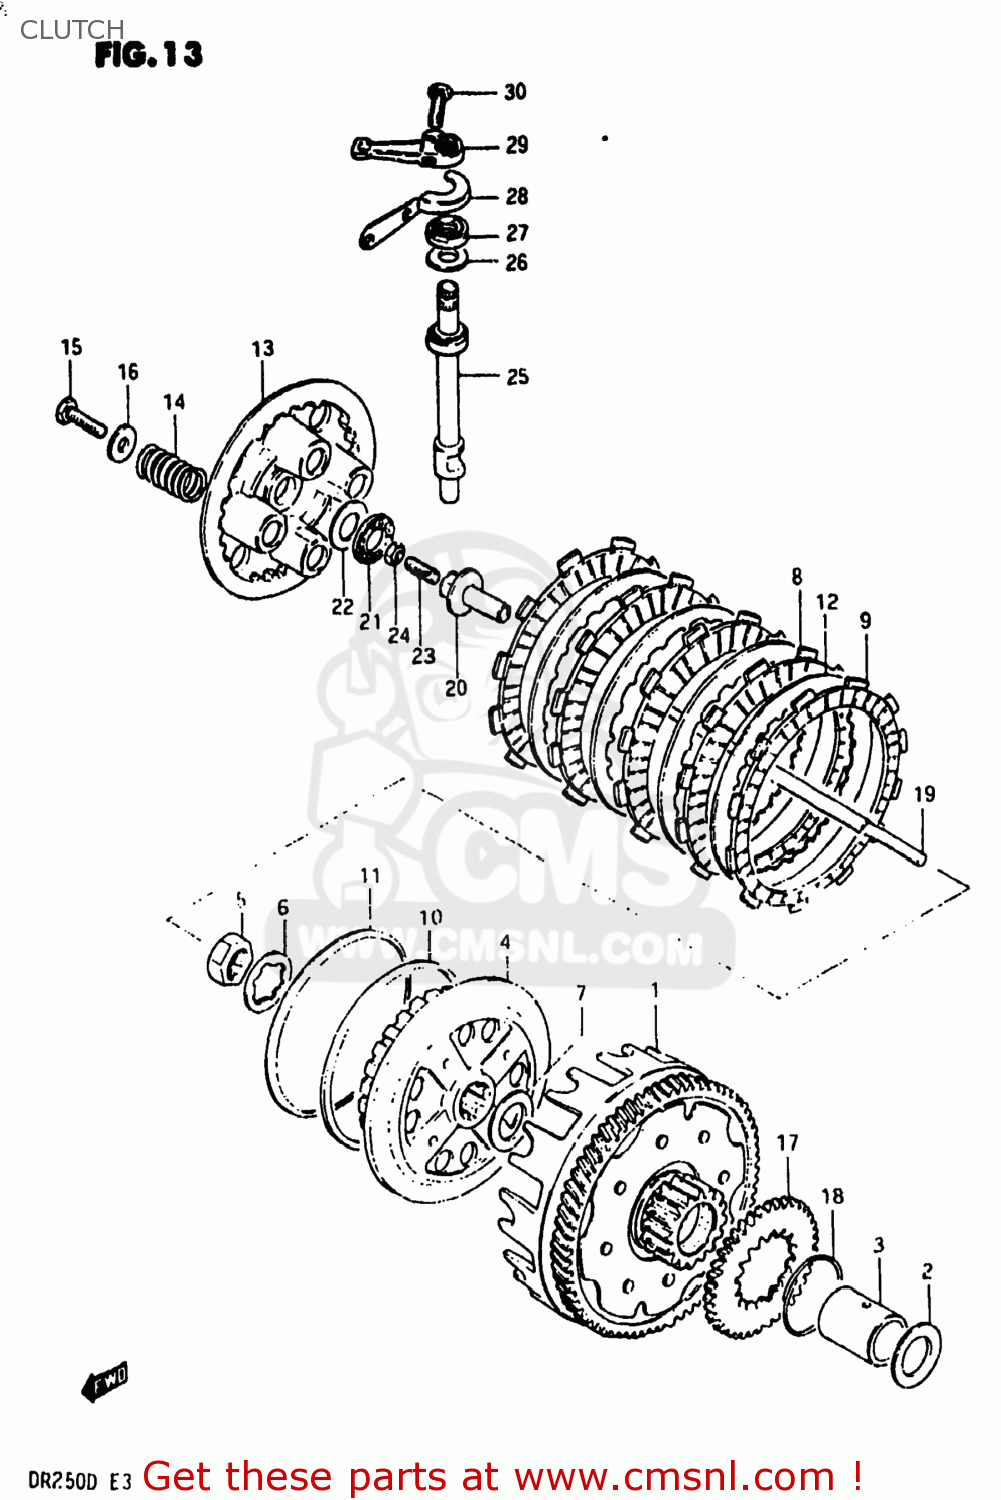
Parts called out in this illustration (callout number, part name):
1	GEAR ASSEMBLY,PRIMARY DRIVE
2	WASHER
3	SPACER(22X28X37.5)
4	HUB,CLUTCH SLEEVE
5	NUT
6	WASHER,LOCK
7	WASHER
8	PLATE,CLUTCH DRIVE (MCA)
9	PLATE,CLUTCH DRIVE
10	SEAT,WAVE WASHER(T:1.4)
11	WASHER
12	PLATE,CLUTCH DRIVEN
13	DISC,CLUTCH PRESSURE
14	SPRING
15	BOLT, UPPER
16	WASHER
17	GEAR,OIL PUMP DRIVE
18	CIRCLIP
19	ROD,CLUTCH PUSH
20	PIECE,CLUTCH PUSH
21	BEARING(15X28X2)
22	WASHER
23	SCREW
24	NUT 6MM
25	CAMSHAFT,CLUTCH RELEASE
26	WASHER (14.2X22X1)
27	OIL SEAL
28	PLATE,RELEASE CAM SHAFT
29	ARM,CLUTCH RELEASE
30	BOLT
